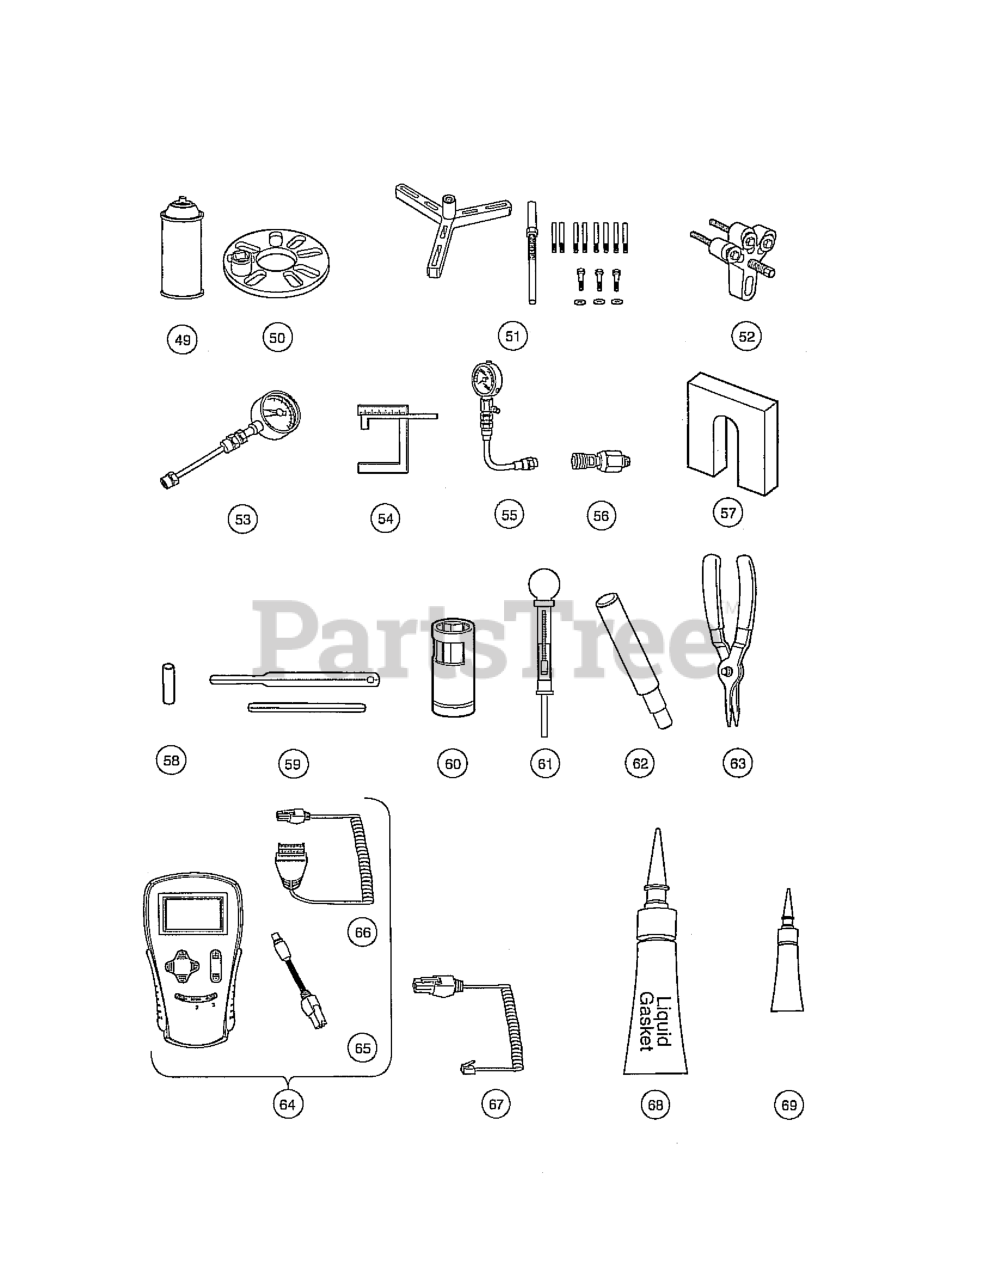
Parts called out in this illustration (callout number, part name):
49	LUBRICANT 11OZ CAN SPRAY
52	FLYWHEEL PULLER KIT
54	GAUGE, CARB FLOAT LEVEL
58	INSERT TOOL, GOVERNOR SHAFT
60	ADJUSTER, HYDRAULIC BRAKE
61	HYDROMETER
63	INERNAL RETAINING RING PLIERS
64	KIT, IQDM, USER, SERIES II
65	ADAPTER, 1307 CABLE
66	CABLE, IQDM, SERIES II
67	CABLE, IQDM
69	LUBRICANT, MOLY-TEFLON, 4 OZ
